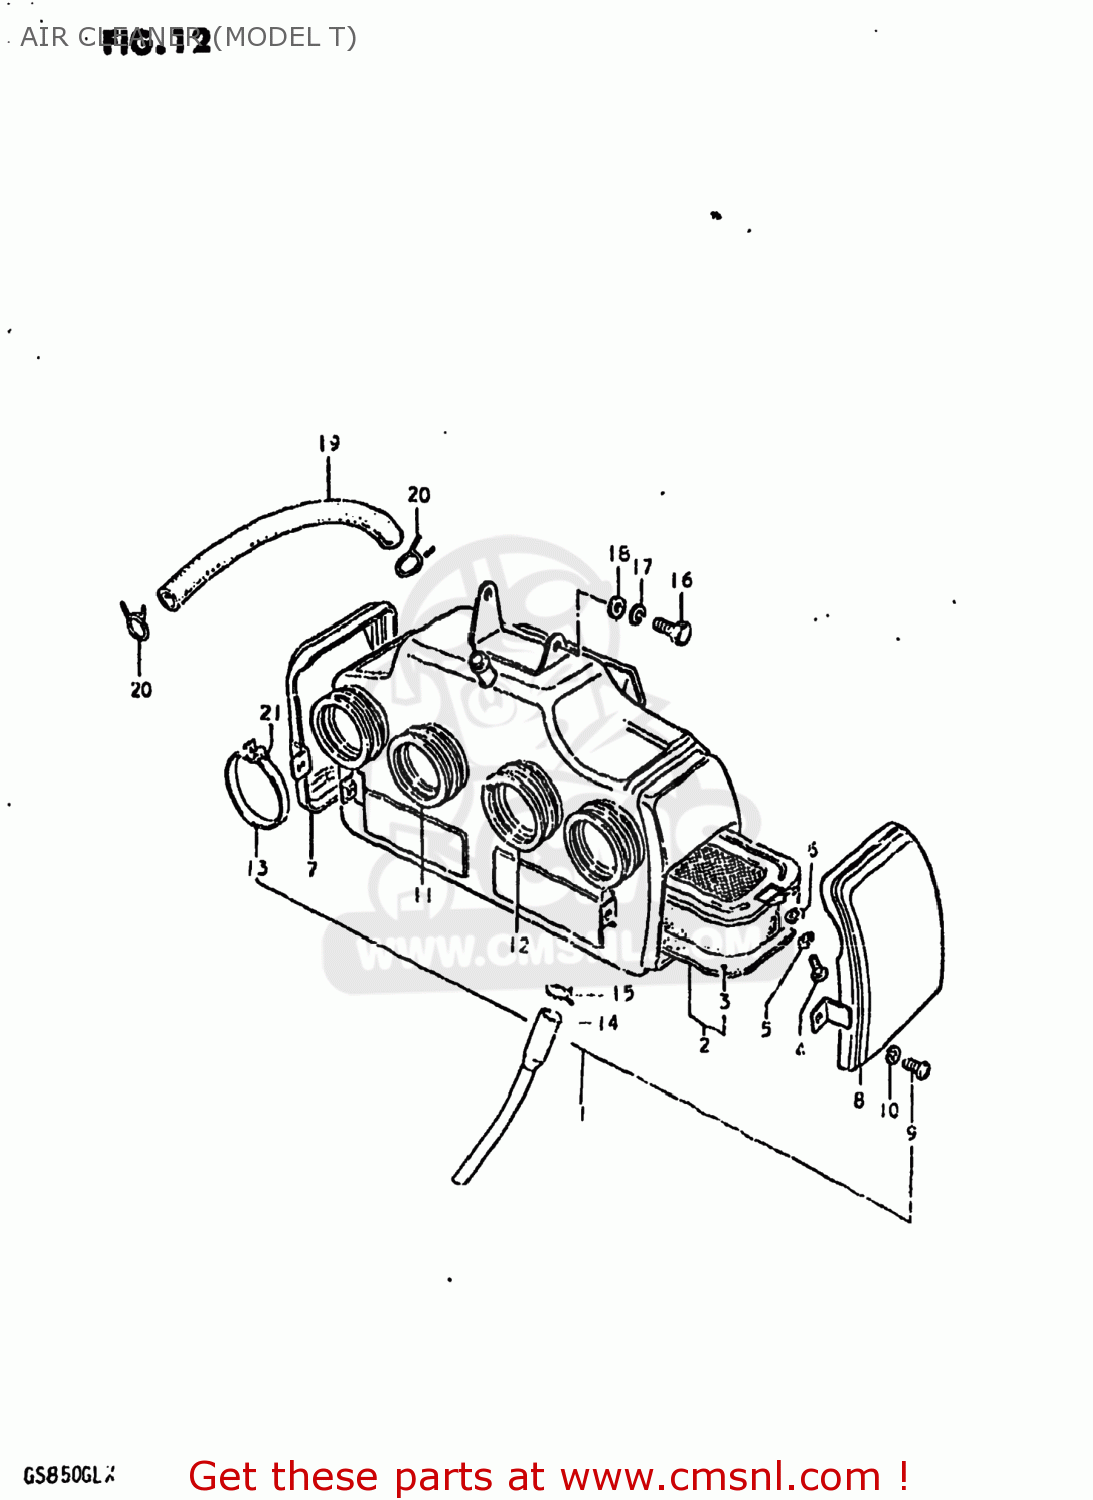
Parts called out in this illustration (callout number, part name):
1	CLEANER ASSEMBLY,AIR
2	FILTER ASSY,AIR CLEANER
3	FILTER
4	SCREW
5	LOCK WASHER
6	WASHER
7	CAP,AIR CLEANER
8	COVER, LH
9	SCREW
10	WASHER
11	HOSE,R
12	HOSE,L
13	CLAMP
14	15
15	16
16	BOLT
17	LOCK WASHER
18	WASHER 6MM
19	HOSE
20	CLIP
